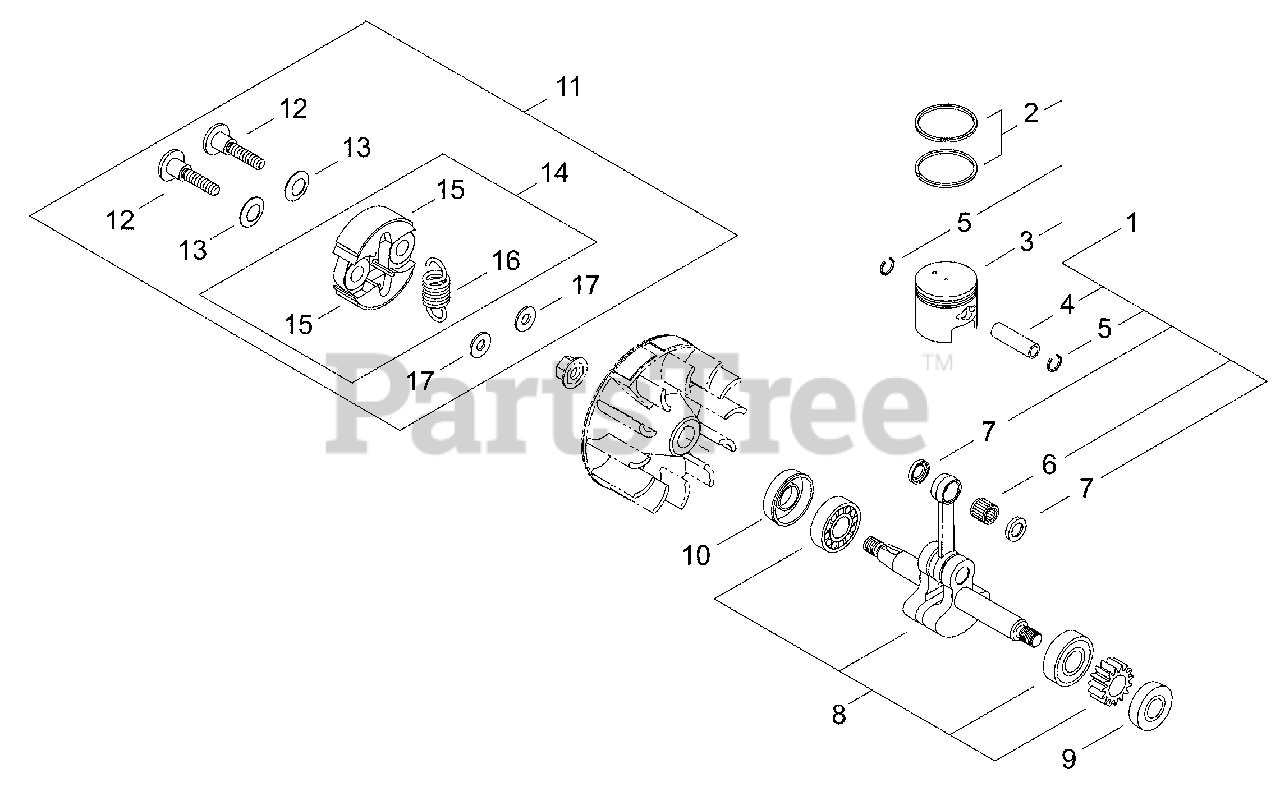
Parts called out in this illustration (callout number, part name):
1	PISTON KIT
2	RING, PISTON
3	PISTON
4	PIN, PISTON
5	RING, SNAP
6	BEARING, NEEDLE 9
7	WASHER, THRUST 9
8	CRANKSHAFT ASSY
9	SEAL, OIL 12
10	SEAL, OIL 12
11	CLUTCH ASSY
12	BOLT, CLUTCH
13	WASHER, SPRING
14	SHOE ASSY, CLUTCH
15	SHOE, CLUTCH
16	SPRING, CLUTCH
17	WASHER 6 MM
